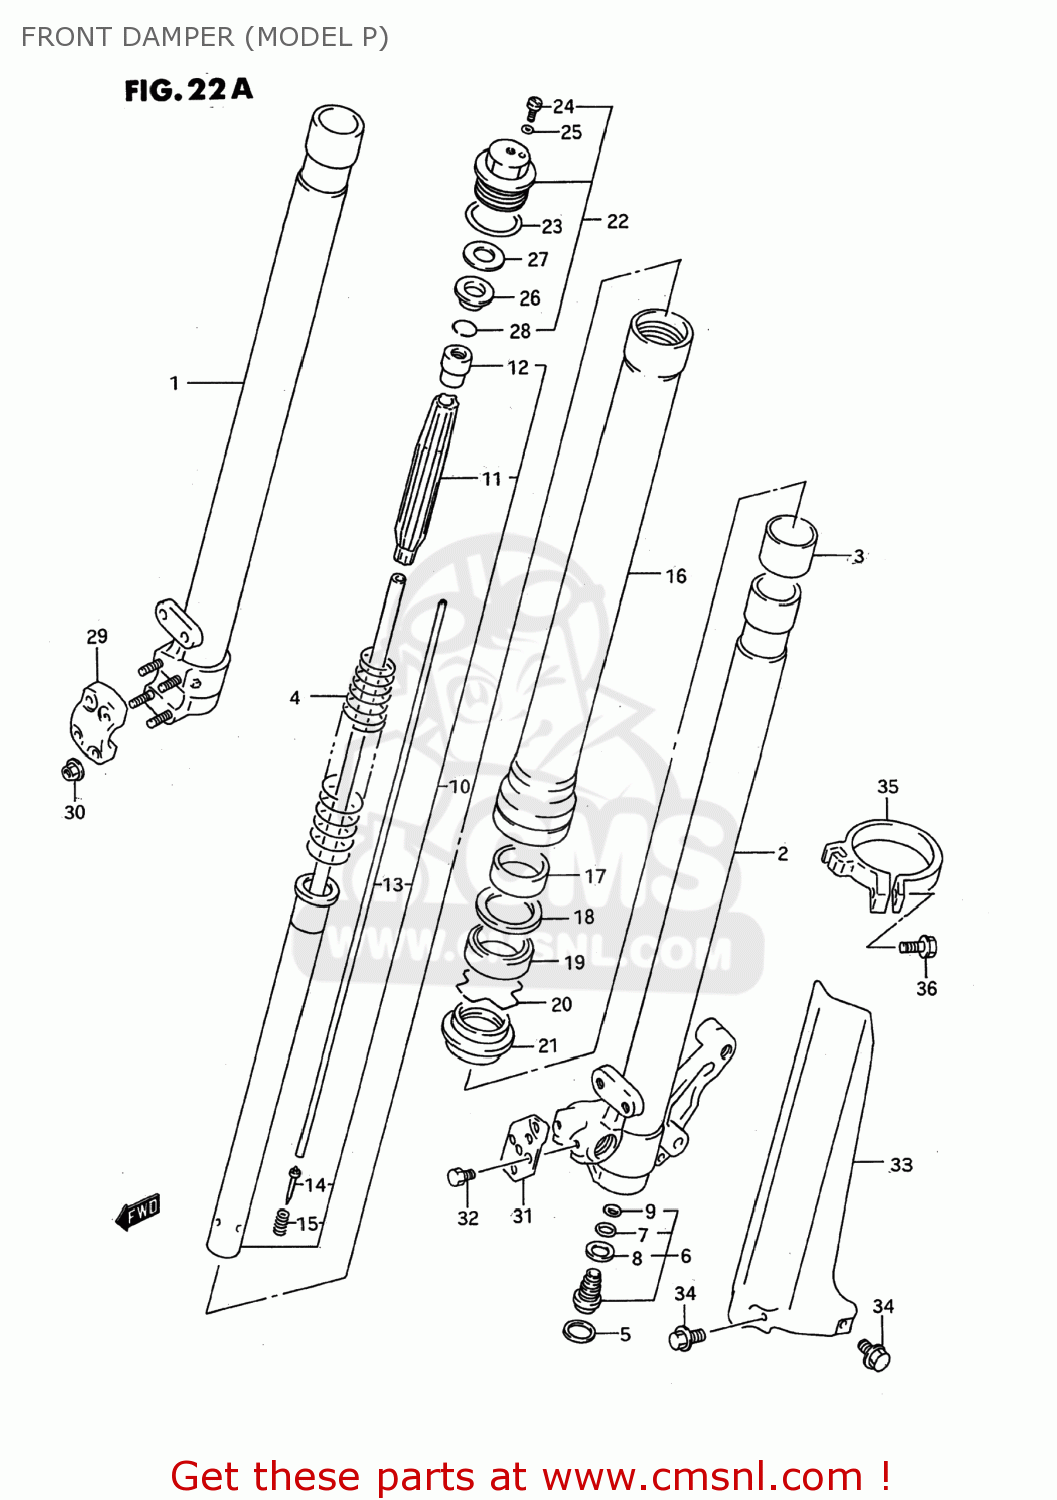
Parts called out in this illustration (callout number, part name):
1	TUBE,INNER,RIGHT
2	TUBE,INNER,L
3	BUSH,SLIDE
4	SPRING,MAIN
5	RING,CTR BOLT STOPPER
6	BOLT ASSY,CTR
7	O RING,CTR BOLT
8	GASKET (NAS)
9	O RING,CTR BOLT UPR
10	DAMPER,FRONT
11	GUIDE,PUSH ROD SPRING
12	NUT,ROD
13	ROD,PUSH
14	NEEDLE
15	SPRING,PUSH ROD
16	TUBE,OUTER
17	BUSH,GUIDE
18	SPACER,SEAL
19	OIL SEAL,FRONT FORK
20	RING,OIL SEAL STOPPER
21	SEAL,DUST
22	BOLT ASSY,FORK
23	O RING
24	BOLT,PLUG
25	O RING
26	SEAT,SPRING
27	WASHER,THRUST
28	RING,STOPPER
29	HOLDER,AXLE,R
30	NUT
31	GUIDE,HOSE,L
32	BOLT 5X16
33	PROTECTOR,FORK,LEFT
34	BOLT,PROTECTOR(6X10)
35	GUIDE,FORK PROTECTOR
36	BOLT,PROTECTOR GUIDE,6
